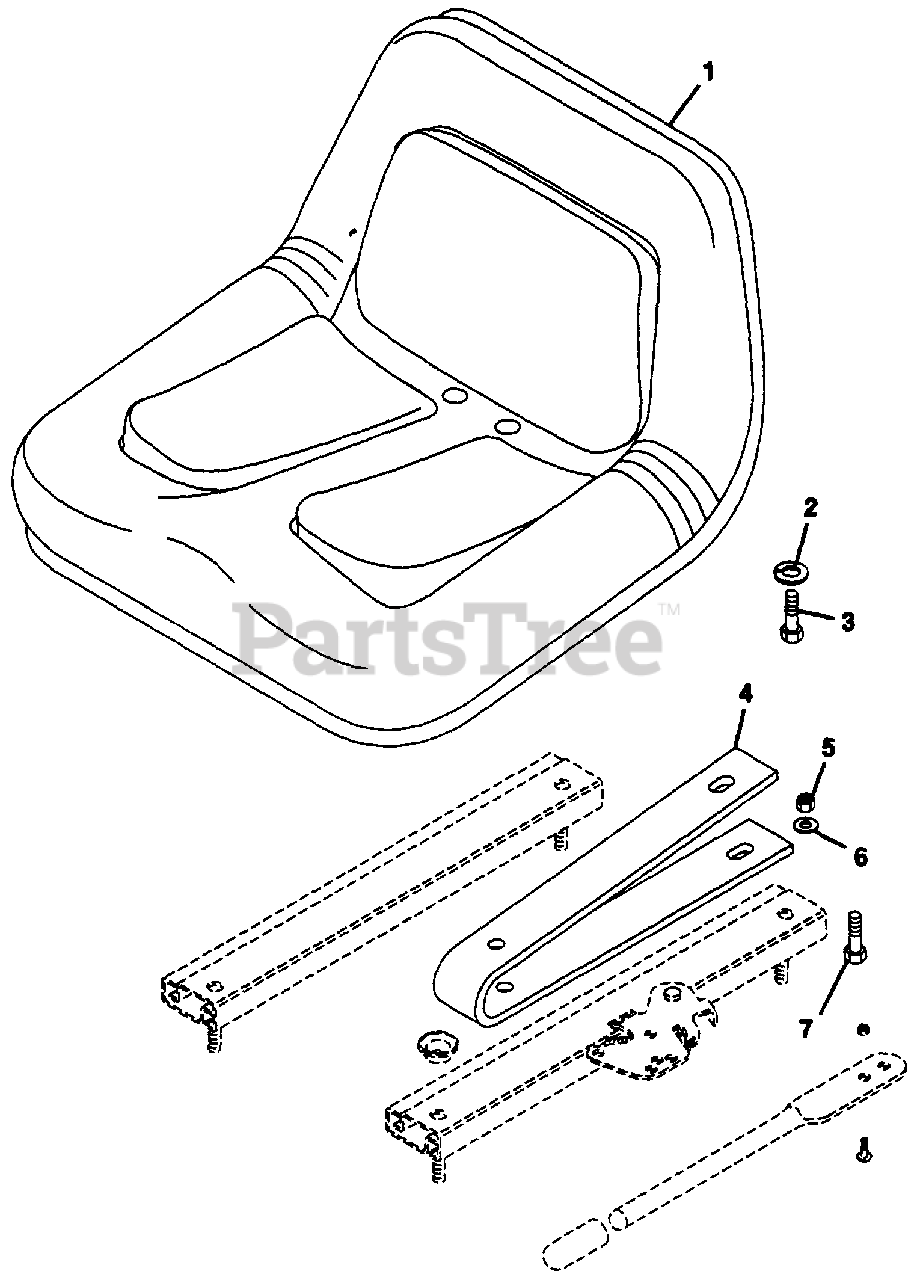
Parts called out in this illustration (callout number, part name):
1	Seat, High Back
2	Washer, Lock 5/16
3	Bolt, Hex 5/16-18x.75
4	Spring, Seat
5	Nut, Lock 5/16-18
6	Washer, Flat .344x.688x.065
7	Bolt, Hex 5/16-18x1.25
